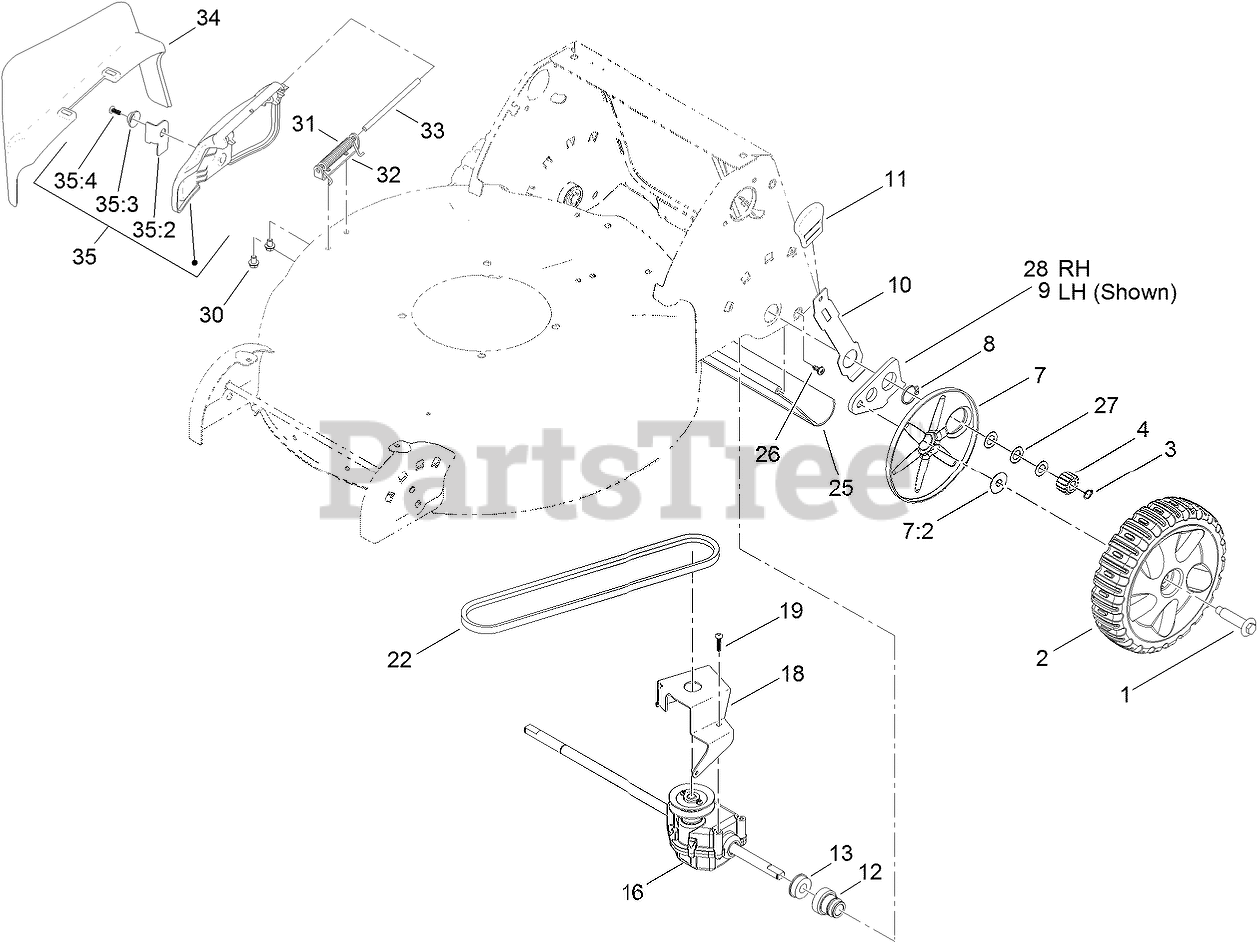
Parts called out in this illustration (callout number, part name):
1	BOLT-SHOULDER
2	8 INCH WHEEL AND GEAR ASM
3	RING-RETAINING
4	GEAR-PINION, 15T
7	WHEEL COVER ASM
7:2	WASHER-STEPPED
8	RING-RETAINING
9	ARM-REAR PIVOT, LH
10	ARM-SPRING, REAR
11	KNOB-HOC
12	RETAINER-BEARING, HOC
13	BEARING-BALL
16	TRANSMISSION ASM
18	BRACKET-TRANSMISSION
19	SCREW-PAN HEAD, T20
22	V-BELT
25	SHIELD-TRAILING
26	SCREW-PTH
27	WASHER-PLAIN
28	ARM-REAR PIVOT, RH
30	SCREW-HWH
31	SPRING-TORSION
32	BRACKET-COVER
33	ROD-COVER
34	CHUTE-DISCHARGE, SIDE
35	DISCHARGE DOOR ASM
35:2	LATCH-DOOR
35:3	CAP-DOOR
35:4	SCREW-PLASTITE
